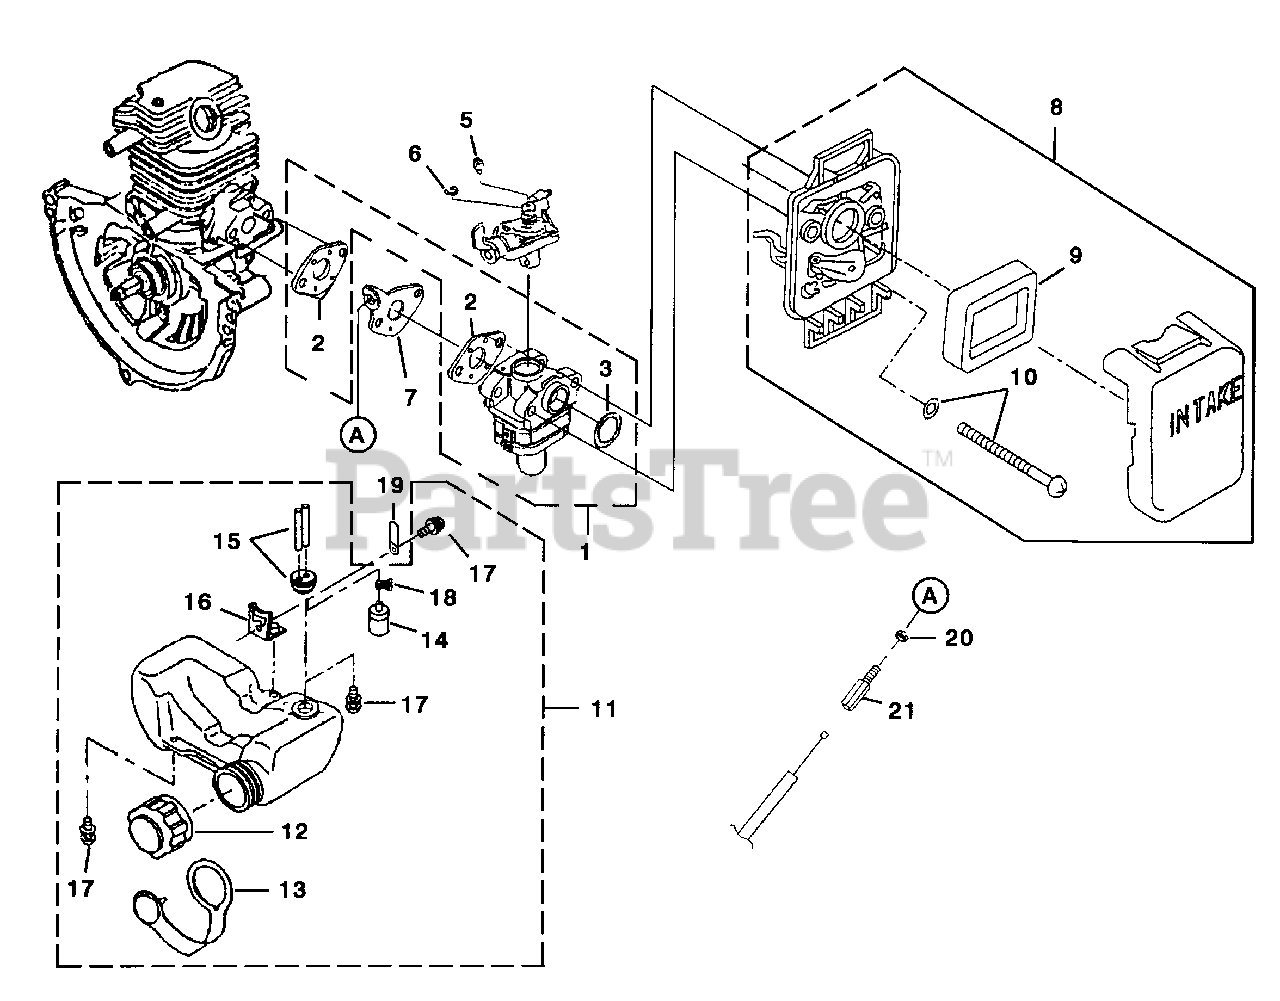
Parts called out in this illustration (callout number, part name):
1	CARBURETOR ASSEMBLY
2	GASKET-Carburetor
7	BRACKET-Cable
8	AIR FILTER ASSEMBLY
9	AIR FILTER
10	SCREW ASSEMBLY (M5 x 65)
11	FUEL TANK ASSEMBLY
12	CAP-Fuel
13	RETAINER-Fuel Cap
14	FILTER-Fuel
15	FUEL LINE ASSEMBLY
16	BRACKET-Fuel Tank
17	SCREW ASSEMBLY (MS x 16)
18	CLAMP-Hose
20	NUT-Cable Adj.
21	SCREW-Cable Adj.
